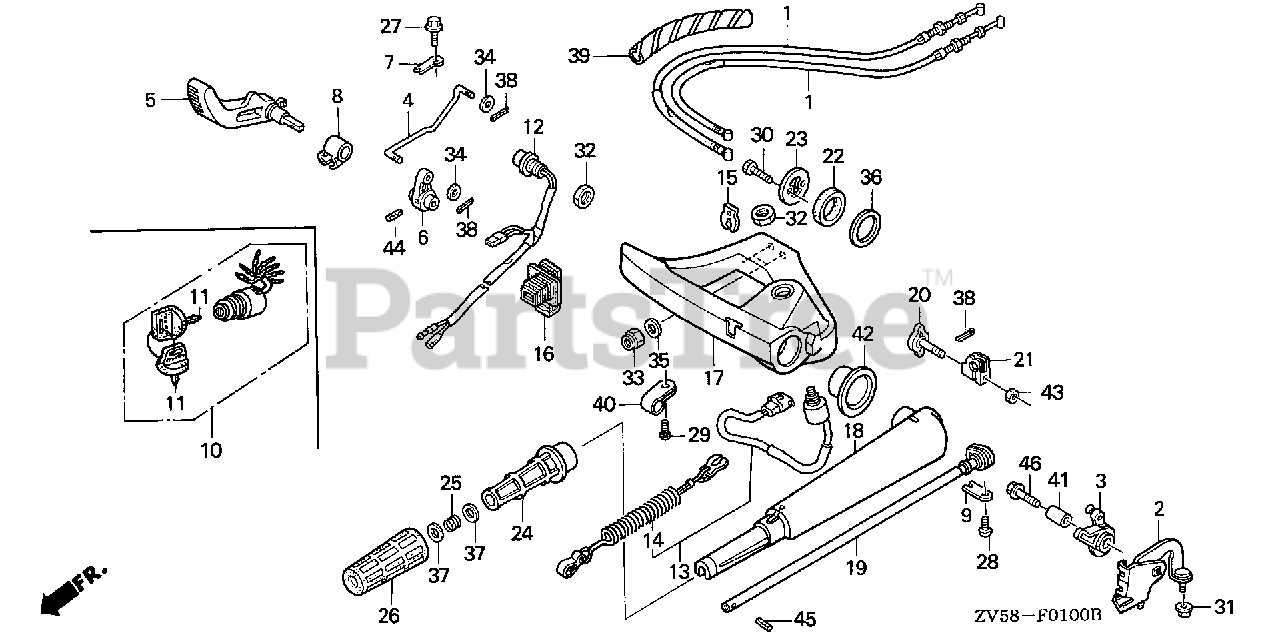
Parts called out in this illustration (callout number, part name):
1	CABLE, THROTTLE
2	BRACKET, THROTTLE CABLE
3	ARM, THROTTLE
5	LEVER, GEARSHIFT
6	LINK, SHIFT (A)
7	PLATE, SHIFT LINK (A)
7	PLATE, SHIFT LINK A
8	COLLAR, DISTANCE
9	PLATE, SHIFT SHAFT
10	SWITCH ASSY., COMBINATION DUAL QTY = (2) (SINGLE)
11	KEY ASSY., COMBINATION SWITCH (35100-ZV5-003 ONLY) DUAL QTY = (4) (SINGLE)
13	SWITCH ASSY., EMERGENCY STOP
14	WIRE, EMERGENCY (SINGLE) (DUAL)
15	CLIP, EMERGENCY LOCK
16	GROMMET, CASE (LOWER) (A)
17	HANDLE, CARRYING *NH282MU* (OYSTER SILVER METALLIC-U)
18	HANDLEBAR *NH282MU* (OYSTER SILVER METALLIC-U)
19	REEL, THROTTLE
20	BOLT, FRICTION
21	BLOCK, THROTTLE FRICTION
22	RUBBER, HANDLE MOUNTING
23	PLATE, HANDLEBAR
24	PIPE, GRIP
25	SPRING, GRIP PIPE
26	RUBBER, GRIP
27	BOLT, FLANGE (6X12) (CT200)
28	SCREW, PAN (6X8)
29	SCREW, PAN (5X12)
30	BOLT, HEX. (6X16)
31	NUT, SELF-LOCK (6MM)
32	NUT, HEX. (16MM) DUAL QTY = (2) (SINGLE)
33	NUT, SELF-LOCK (10MM)
34	WASHER, PLAIN (5MM)
35	WASHER (10MM)
36	WASHER, HANDLEBAR (36MM)
37	WASHER (10MM)
38	PIN, SPLIT (2.0)
39	TUBE, SPIRAL
40	CLIP, WIRE HARNESS (6.3MM)
41	COLLAR, DISTANCE (6.5X10.5X16)
42	COLLAR, HANDLEBAR
43	NUT, HEX. (6MM)
44	PIN, SPRING (4X20)
45	PIN, SPRING (4X28)
46	BOLT, FLANGE (6X28)
